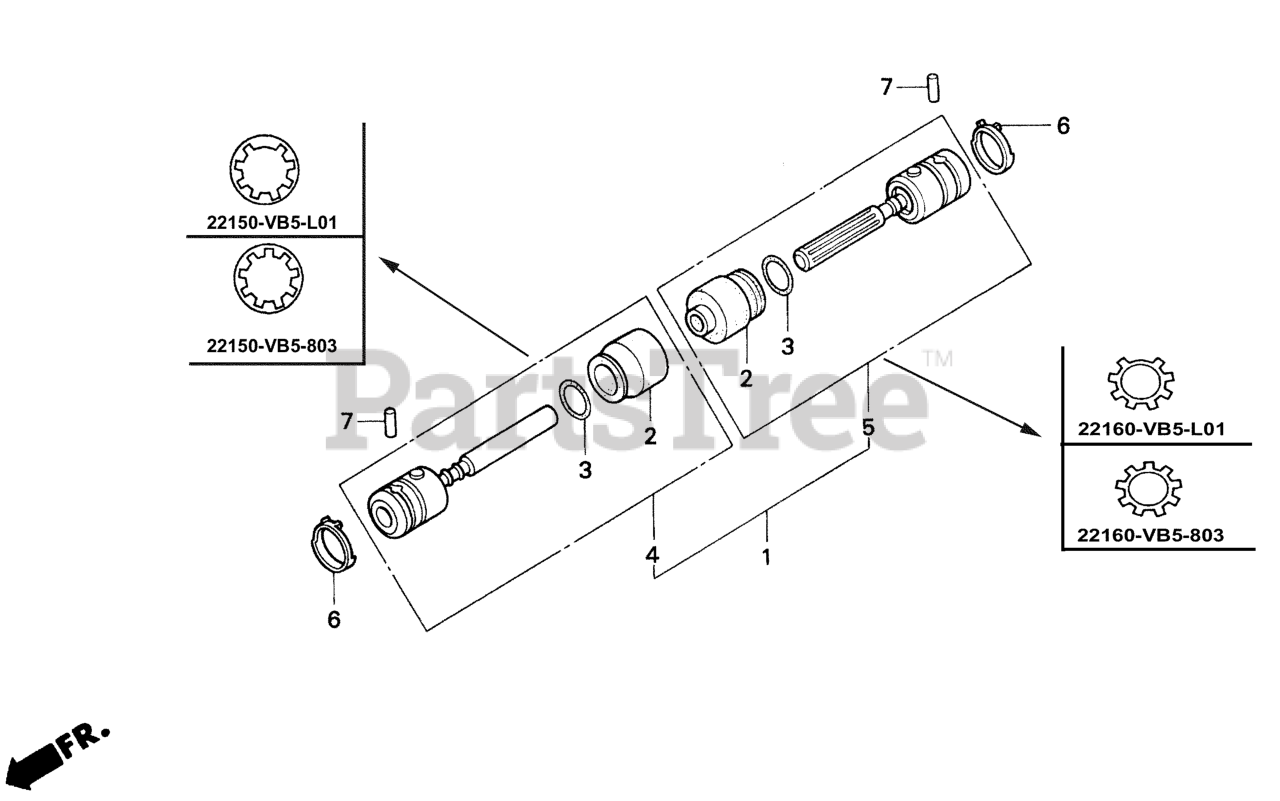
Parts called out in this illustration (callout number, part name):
1	JOINT ASSY.
2	BOOT, JOINT
3	RING, SEAL
4	JOINT SUB-ASSY. (A)
5	JOINT SUB-ASSY. (B) (NA USE ALT:22100-VB5-L01)
5	JOINT SUB-ASSY. (B)
6	CLIP, CLUTCH SHAFT
7	ROLLER (4X17.8)
